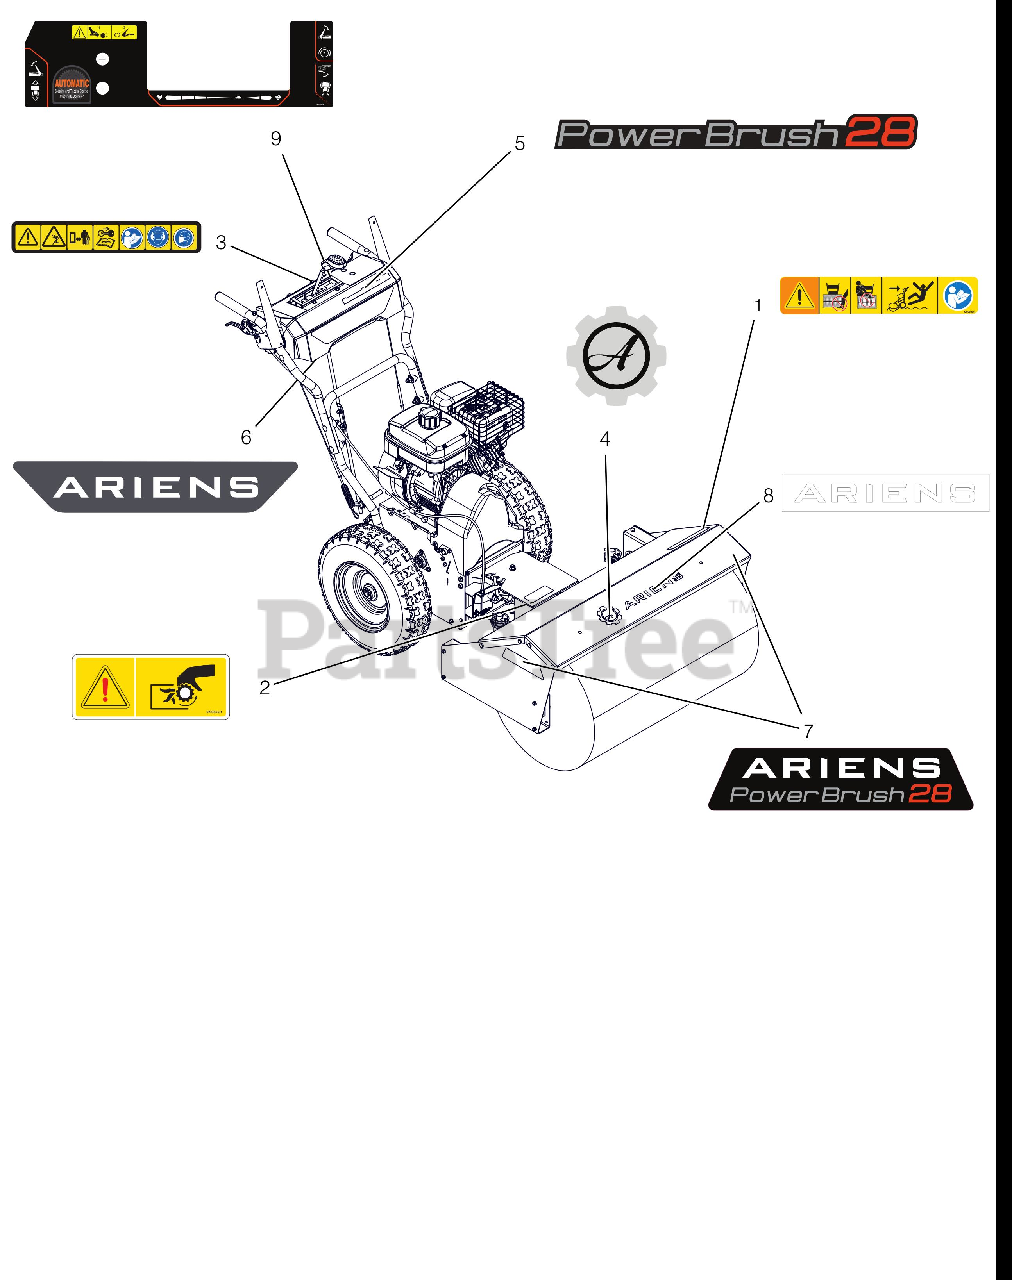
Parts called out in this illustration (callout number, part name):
1	DECAL, DANGER -POWER BRUSH-CE
2	DECAL, PTO WARNING
3	DECAL, SAFETY, DASH, BRUSH
4	DECAL, ARIENS-GEAR BADGE
5	DECAL, DASH - PB 28
6	DECAL, DASH BRAND - ARIENS PB
7	DECAL - ARIENS PB 28
8	DECAL - ARIENS 9.625"
9	DECAL,CONTROL,SMALL BRUSH
